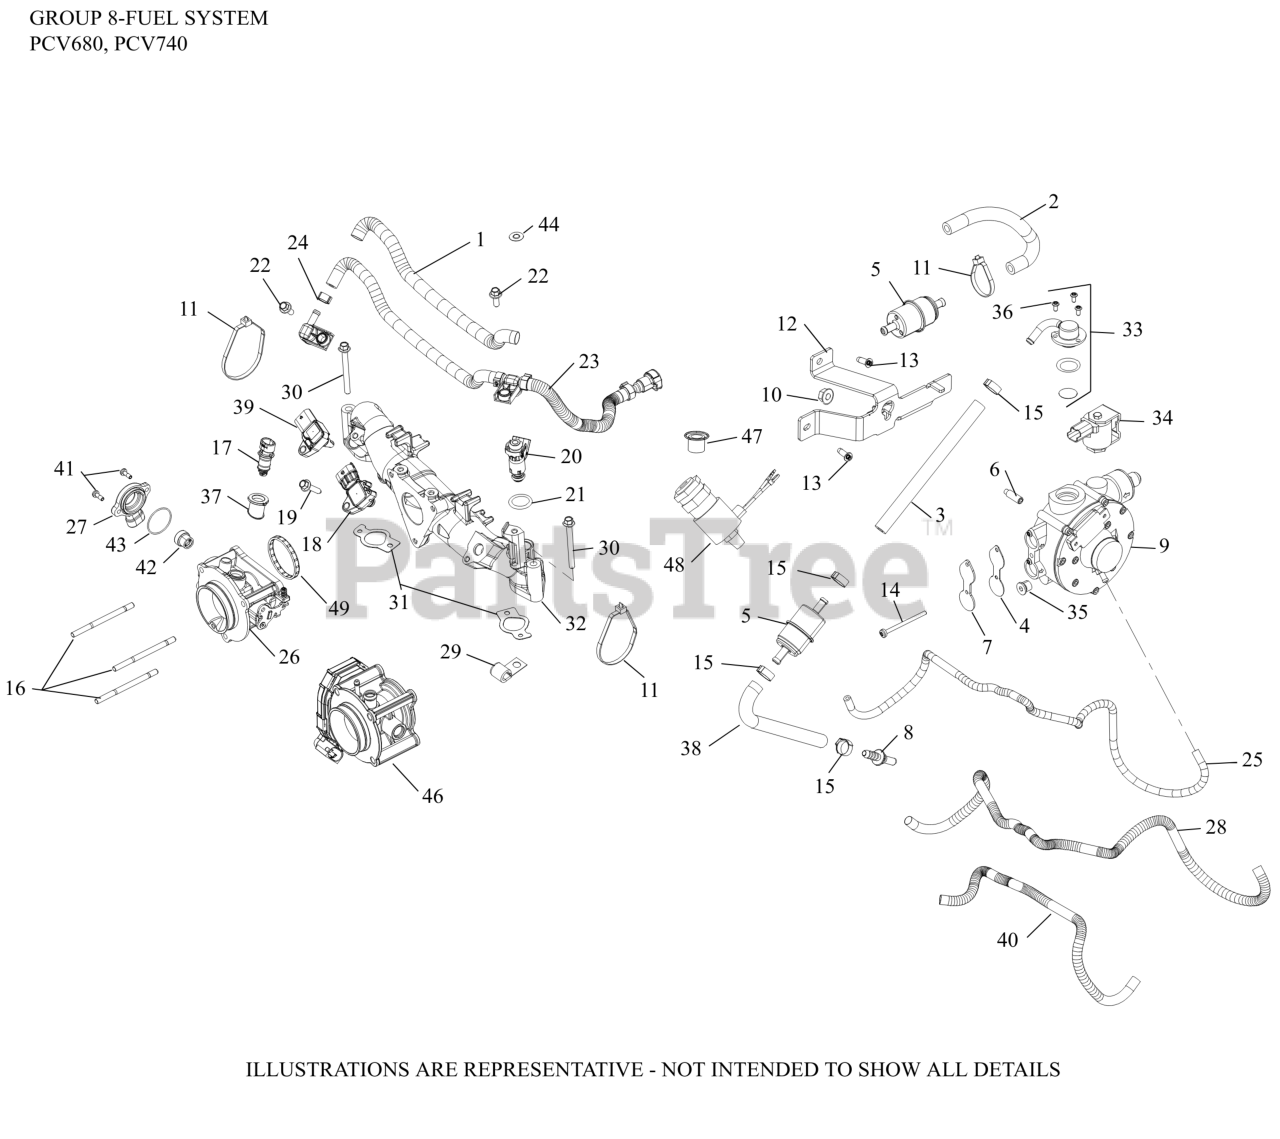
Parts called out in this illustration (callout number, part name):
1	SLEEVE, ANTI ABRASION -USE 25 431 12-S
2	HOSE, FUEL LOW PERMEATION
3	HOSE, FUEL LOW PROPANE
5	PROPANE FUEL FILTER KIT
6	STUD, LP REGULATOR
7	COVER, OIL PORT
8	FITTING, FUEL - STRAIGHT
9	REGULATOR, W/RTV
10	NUT, FLG M8X1.25
12	BRACKET, LP REGULATOR
13	SCREW, THREAD FORMING
15	CLAMP, HOSE
16	STUD,M6X1.0X84
17	SENSOR, AIR TEMPERATURE
18	SENSOR, MAP
19	SCREW, FLG M6X1.0X25
20	INJECTOR, GASEOUS FUEL
21	KIT, FUEL INJECTOR O-RING
22	SCREW, FLG M6x1.0x20
23	FUEL HOSE ASSY PCV680 THRU PCV740
24	CLAMP, OETIKER
25	HOSE, EVAPORATIVE
26	KIT, THROTTLE BODY ASSEMBLY
27	SENSOR, THROTTLE POSITION
28	SLEEVE, ANTI ABRATION
30	SCREW, FLG M6X1.0X40
30	SCREW, FLG M6X1.0X60
31	GASKET, INTAKE MANIFOLD-USE 24 041 79-S
32	KIT, MANIFOLD
33	KIT, OUTLET FITTING W/O-RING LPG
34	KIT, LOCK-OFF ASSY LPG (A7-175)
35	KIT, PLUG W/O-RING LPG (A7-173)
36	SCREW, STARTER SWITCH
37	GROMMET, AIR TEMP SENSOR
40	SLEEVE, ANTI-ABRASION
45	SCREW, HEX SOCKET HEAD CAP
NI	KIT, VAPORIZER FILTER REPL'MT LPG(A7-170
